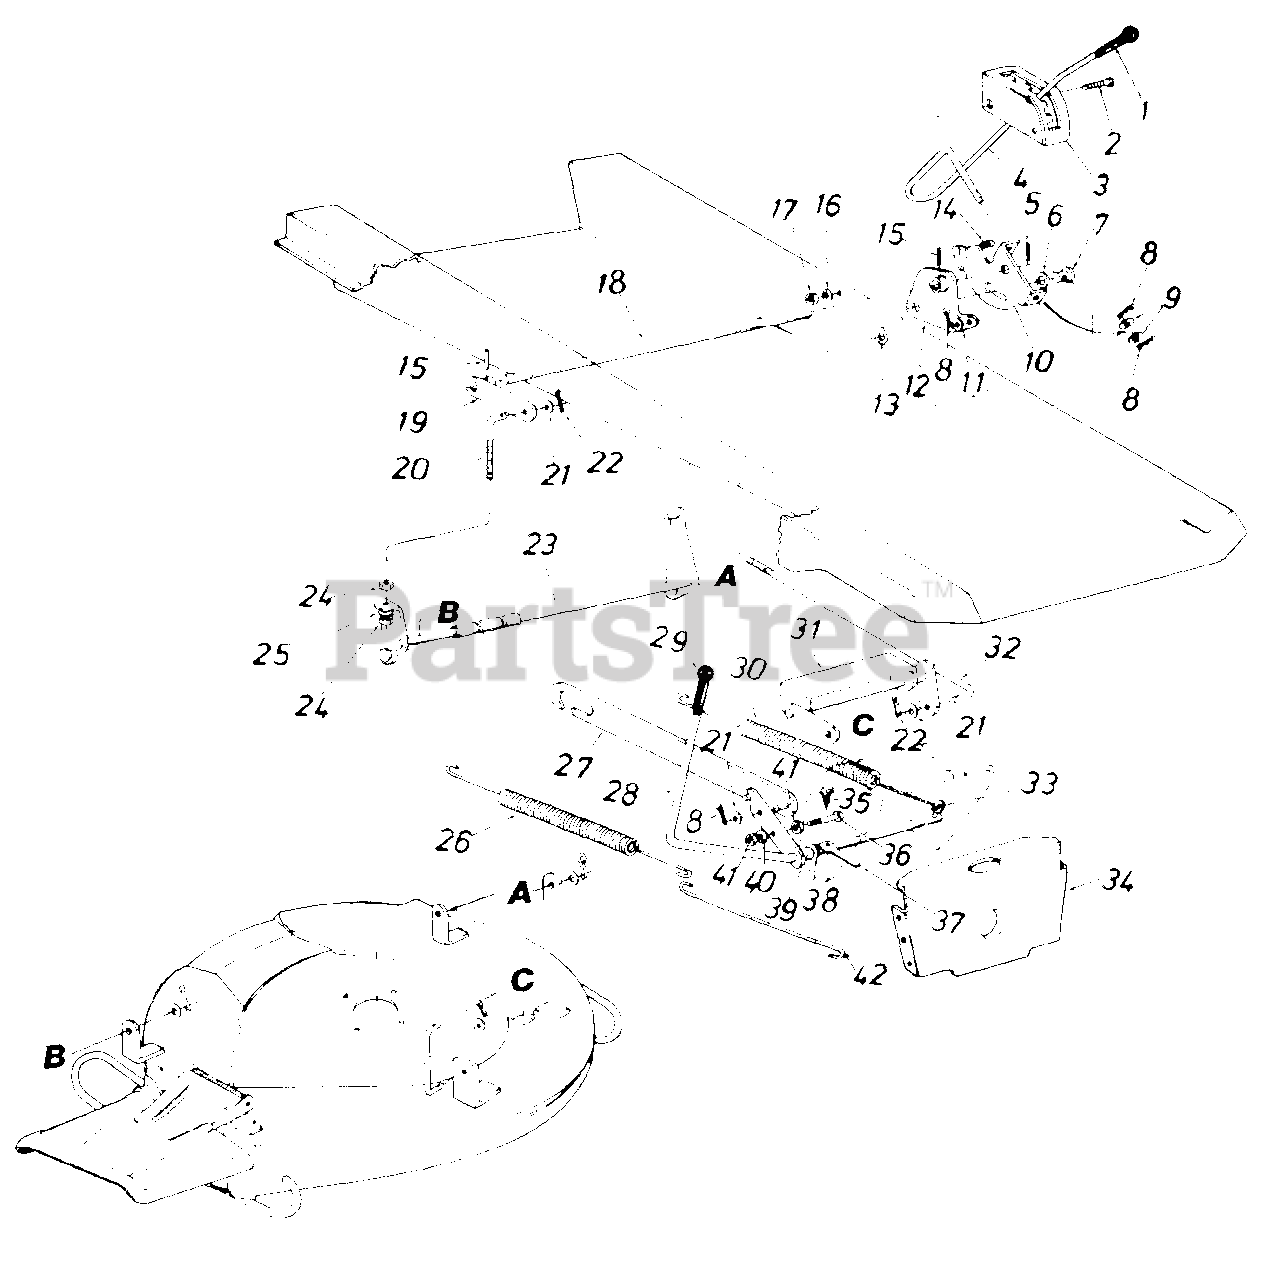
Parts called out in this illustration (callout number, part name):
2	Truss Mach. Scr. 5/16-18 x .75" Lg.
5	Spring Pin Spir. 3/16" Dia. x 1.50" Lg.
6	Fl-Wash. .385" I.D. x .87" 0. D.
7	Adj. Ferrule Deck Lift Handle
8	Cotter Pin 1/8" Dia. x 1.00" Lg.
9	Fl-Wash. .531" I.D. x .930" O.D.
10	Deck Lift Handle Retainer Ass'y.
11	Fl-Wash. .385" I.D. x .87" 0. D.
12	Deck Lift Brkt. Ass'y. L.H.
13	Fl-Wash. .635" I.D. x 1.04" 0. D.
14	Compression Spring .50" Dia. x 1.0" Lg.
15	Spring Pin Spir. 1/4" Dia. x 1.50" Lg.
16	L-Wash. 5/16" I.D.
17	Hex Nut 5/16-18 Thd.
18	Rear Hgt. Adj. Shaft
19	Deck Lift Brkt. Ass'y. R.H.
20	Deck Adj. Scr. 3/8-16 Thd.
21	Fl-Wash. .385" I.D. x .87" O.D.
22	Intern. Cotter Pin 1/2" Dia.
23	Deck Link Ass'y. Rear
24	Hex Nut 3/8-16 Thd.
25	L-Wash. 3/8" I.D.
26	Extension Spring .73" O.D. x 13.84" Lg.
27	Deck Drive Control Bracket
28	Blade Engagement Lever Ass'y.
30	Extension Spring .73" O.D. x 13.89" Lg.
31	Deck Lift Ass'y. Front
32	Deck Lift Connecting Rod
33	Clevis Pin Special .250" Dia.
34	Pivot Bar Bracket
35	Hex TT-Tap Scr. 1/4-20 x .75" Lg.
36	Hex Bolt 5/16-18 x 1.50" Lg. (Grade 5)
37	Switch Actuator
38	Fl-Wash. .531" I.D. x .930" 0. D.
39	Spacer .511" I.D. x .70" O.D. x.38" Lg.
40	L-Wash. 5/16" I.D.
41	Hex Nut 5/16-18 Thd.1"
